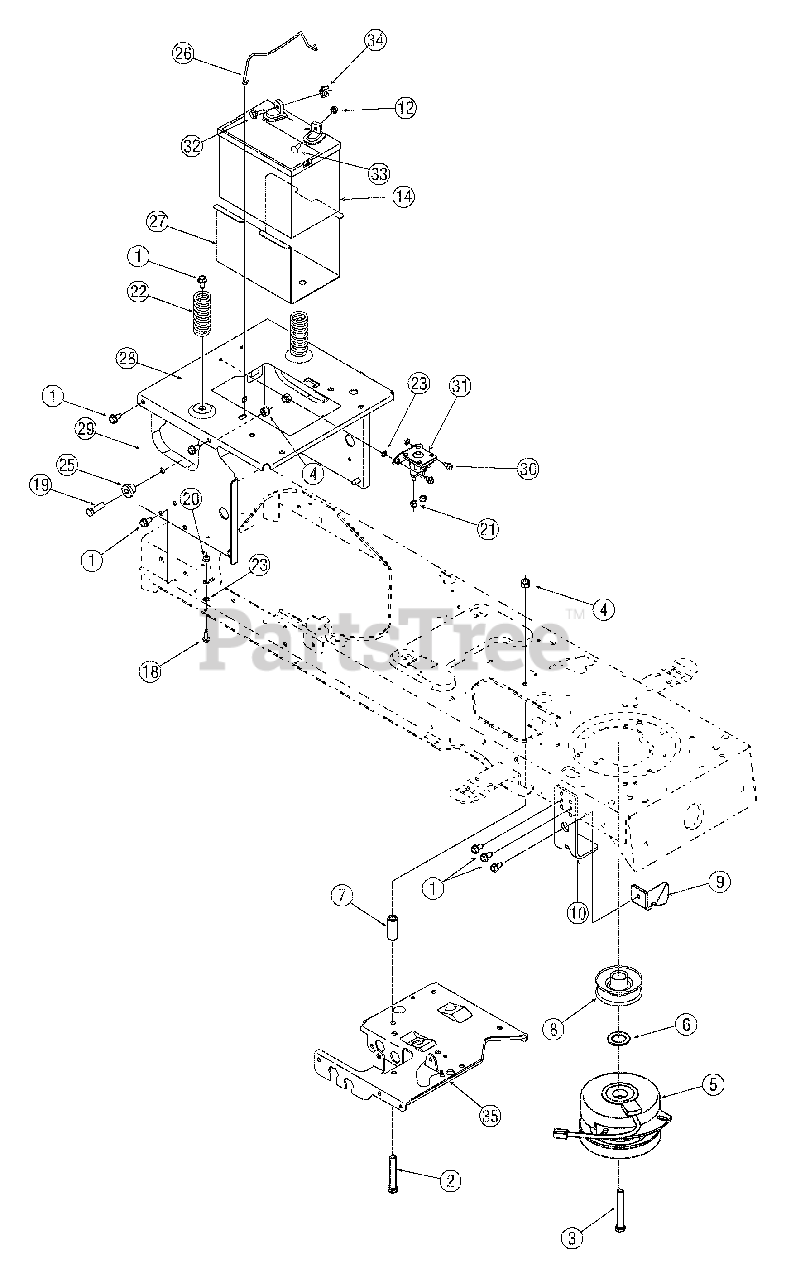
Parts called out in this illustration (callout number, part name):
1	Screw, 5/16-12, 0.75
2	Screw, 3/8-16, 2.50, Gr5
3	Screw, 7/16-20, 3.25, Gr5, Lock
4	Nut, Flange Lock, 3/8-16, Gr F, Nylon
5	PTO Clutch, Electric
6	Washer, Flat, 1.031 x 1.620 x.095
7	Spacer, .385 ID x .635 OD x 1.54
8	Pulley, Engine, 3.56 Diameter
11	Screw, Carriage, 1/4-20, .75, Gr5
12	Nut, Sems, 1/4-20
13	Nut, Wing, 1/4-20
14	Battery, 235 CCA
15	Screw, Shoulder, .250 x .150, 1/4-20
18	Screw, 1/4-20, 0.750
19	Screw, 3/8-16, 1.25, Gr5
20	Nut, Flange Lock, 1/4-20, Gr F, Nylon
21	Nut, Hex, 1/4-20, Gr5
22	Spring, Compression, 1.28 OD x 3.125
23	Washer, Lock, 1/4, External
24	Washer, Lock, 1/4
25	Spacer, Shoulder, .38 x 1.0 x .70
26	Hold Rod, Battery
30	Screw, 1/4-20, 0.50
31	Solenoid, 12V, 100 Amp
32	Screw, Shoulder, .250 x .15, 1/4-20
33	Screw, Carriage, 1/4-20, .75
34	Nut, Wing, 1/4-20
